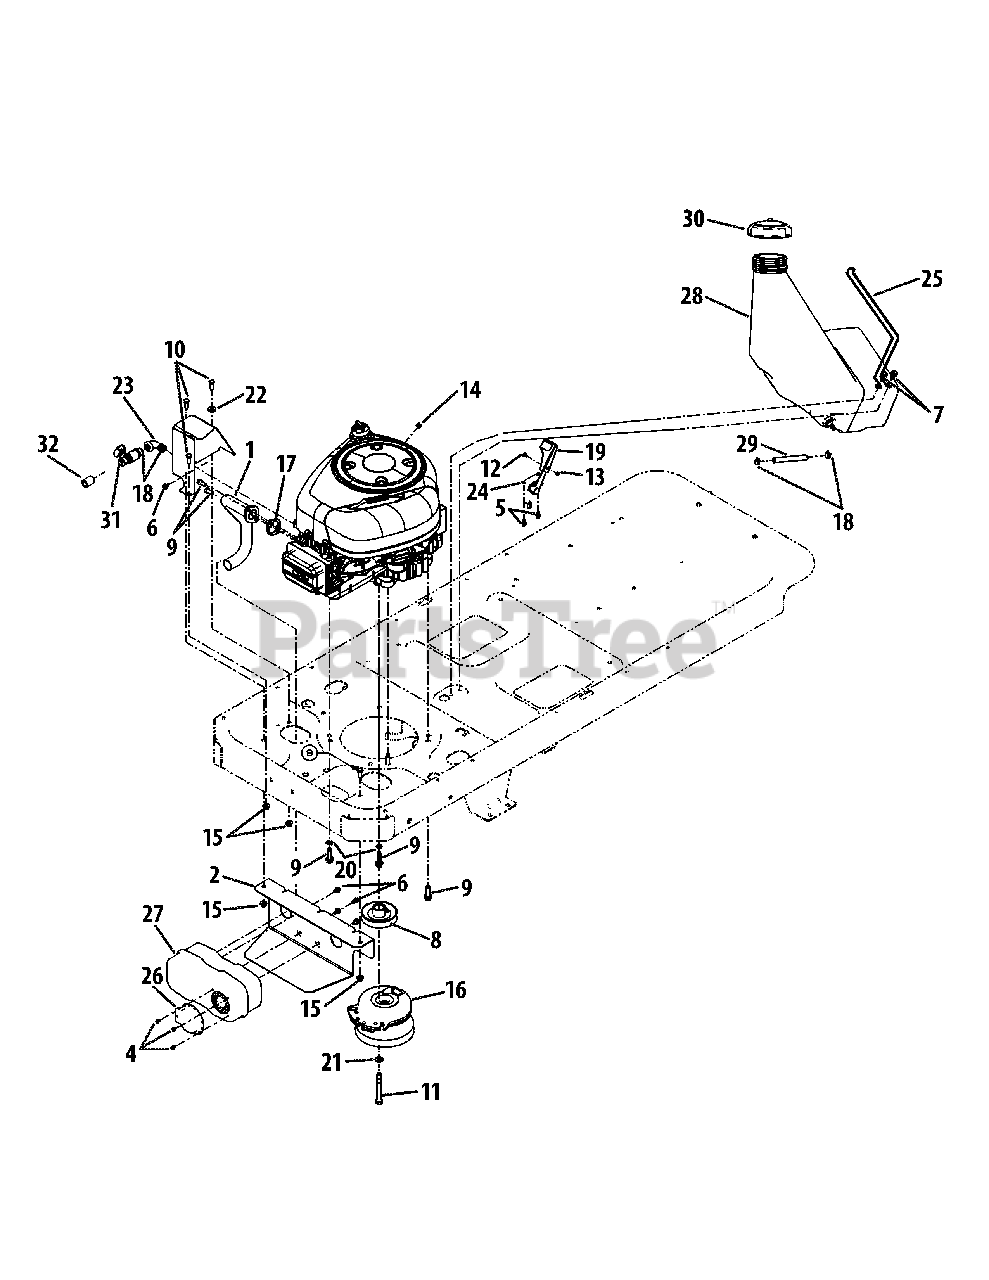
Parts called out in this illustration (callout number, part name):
1	Exhaust Tube
2	Muffler Mounting Bracket
3	Muffler Tube Heat Shield
4	Hex Wsh. Hd. Screw, #8-18 x .5
5	Hx. Wsh. Hd. Screw, #12-16 x .5
6	Hx. Wsh. Hd. Screw, 1/4-20 x .5
7	Hx. Wsh. Hd. Screw, 5/16-12 x .75
8	Drive Pulley
9	Hx. Wsh. Hd. Screw, 3/8-16 x 1.25
10	Hex Cap Screw, 5/16-18 x .75
11	Hx Cap Lk. Screw, 7/16-20 x 3.25
12	Truss Hd. Mach. Screw, #8-32 x .375
13	Hex Nut, #8-32
14	Hex Sems Nut, 1/4-20
15	Hx. Insert Flange Lck Nut, 5/16-18
16	Electric PTO Clutch Assembly
17	Exhaust Gasket (272293)
18	Hose Clamp
19	Throttle Control Knob
20	Ext. Tooth Lock Washer, 3/8
21	Lock Washer, 7/16
22	Flat Washer, .344 x .75 x .12
23	Elbow Fitting
24	Throttle Cable, 39.0 Lg
25	Tank Mounting Wire
26	Muffler Deflector
27	Muffler
28	Fuel Tank, 3.0 Gal.
29	Fuel Line Hose
30	Fuel Cap
31	Oil Drain Valve
32	Oil Drain Extension Hose
